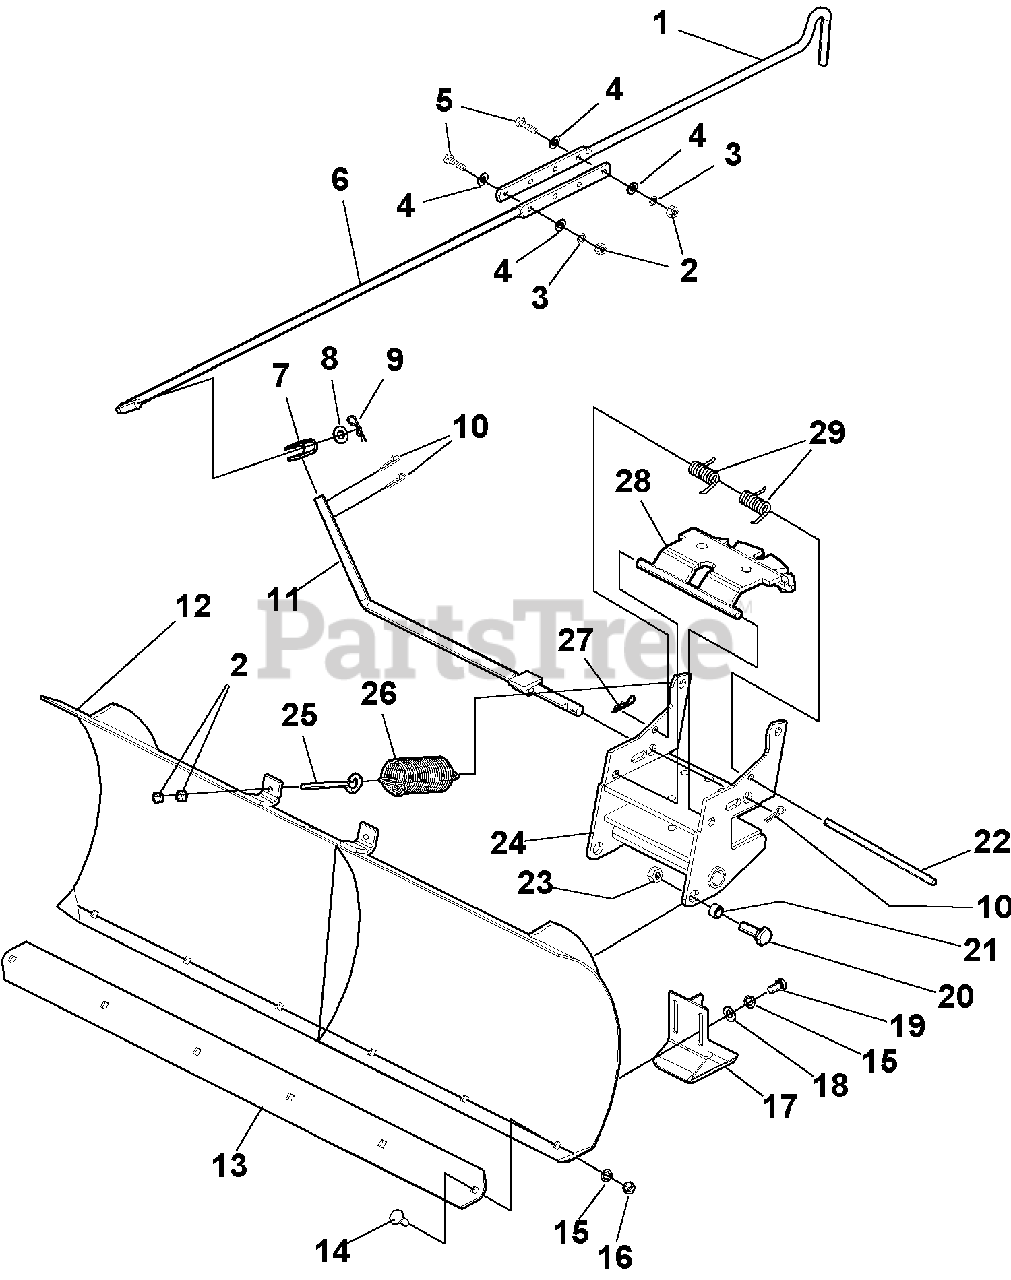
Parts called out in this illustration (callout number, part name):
2	NUT, Hex, 5/16-18
3	LOCKWASHER, 5/16
4	WASHER, 5/16
5	CAPSCREW, Hex Head, 5/16-18 x 1-1/4
6	ROD, Control
7	CLEVIS
8	WASHER,1/2
9	PIN, Hair
10	PIN, Cotter
11	ROD & PLATE ASSEMBLY
12	BLADE ASSEMBLY
14	CARRIAGE BOLT,3/8-16 x 1
15	LOCKWASHER, 3/8
16	NUT, Hex, 3/8-16
17	SHOE ASSEMBLY
18	WASHER, 3/8
19	CAPSCREW, Hex Head, 3/8-16 x 3/4
20	CAPSCREW, Hex Head, 1/2-13 x 1-1/2
23	NUT, Hex Centerlock, 1/2-13
24	FRAME ASSEMBLY
27	PIN, Hair
28	PLATE ASSEMBLY
